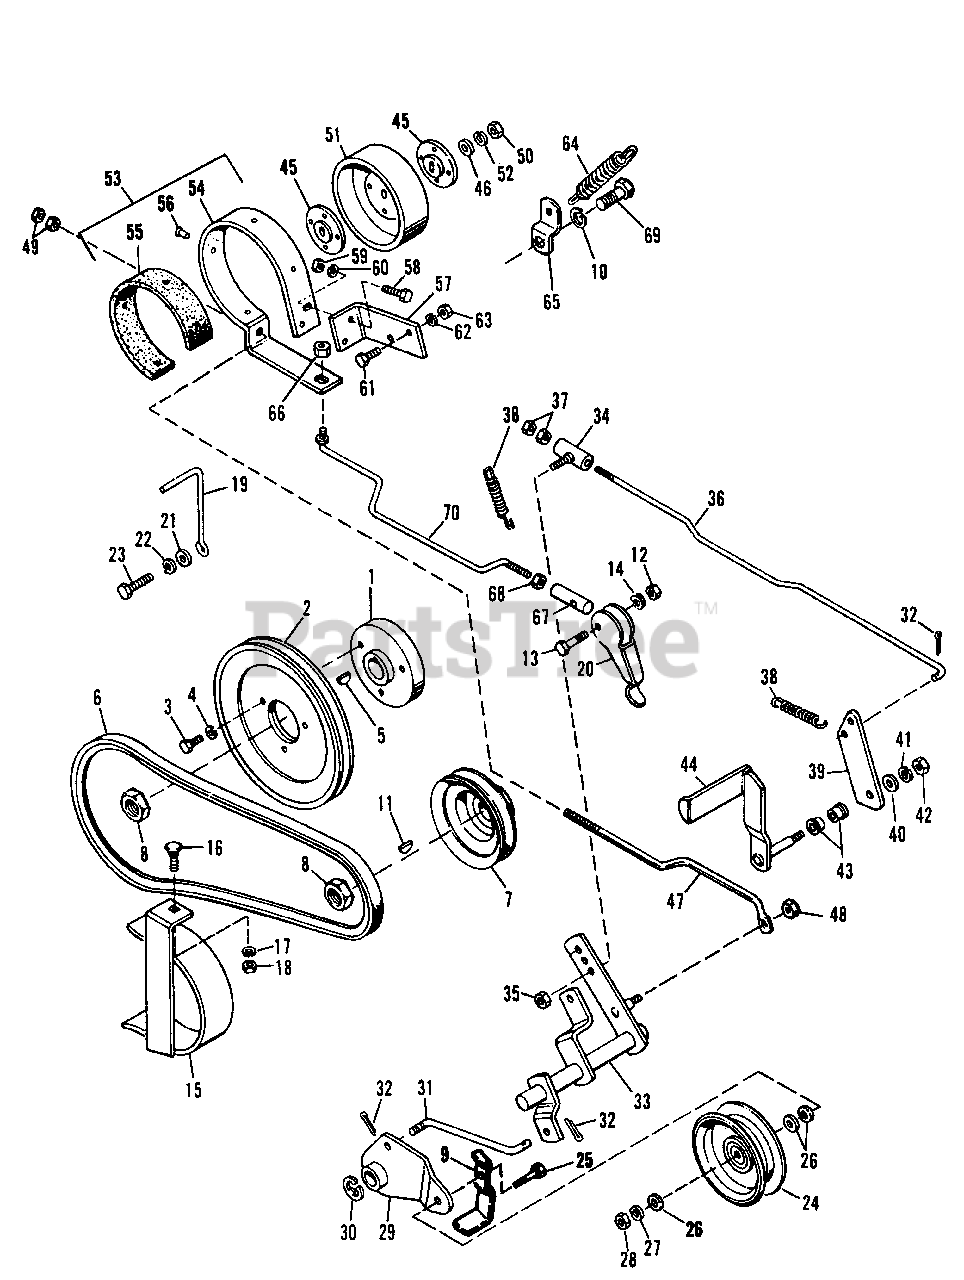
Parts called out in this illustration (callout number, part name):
1	HUB, Pulley
2	PULLEY, Drive
3	CAPSCREW, Hex, 5/16"-18 x 7/8" lg.
4	LOCKWASHER, 5/16"
5	KEY
6	V-BELT, 49.1"
8	NUT, Hex, Jam, 3/4"-16
9	GUIDE, Belt
10	LOCKWASHER, 7/16"
11	KEY
12	NUT, Hex, Full, Lock, 1/4"-20
13	CAPSCREW, Hex, 1/4"-20 x 1-1/4" lg.
14	LOCKWASHER, Double, 1/4"
15	GUARD ASSEMBLY, Belt
16	BOLT, Carriage, 3/8"-16 x 3/4" lg.
17	LOCKWASHER, 3/8"
18	NUT, Hex, Full, 3/8"-16
20	LEVER, Brake, Parking
21	WASHER, Plain, 3/8"
22	LOCKWASHER, 3/8"
23	CAPSCREW, Hex, 3/8"-16 x 1" lg.
24	PULLEY
25	CAPSCREW, Hex, 3/8"-16 x 1-1/2" lg.
26	WASHER, Plain, 3/8"
27	LOCKWASHER, 3/8"
28	NUT, Hex, Full, 3/8"-16
29	LEVER ASSEMBLY, Idler
30	"E" RING
31	LINK, Clutch
32	PIN, Cotter
33	LEVER ASSEMBLY, Pivot
34	GUIDE ASSEMBLY, Rod
35	NUT, Hex, Full, Lock, 5/16-18
36	ROD ASSEMBLY, Brake & Clutch
37	NUT, Hex, Full, 5/16-18
39	ARM, Pedal, Foot
40	WASHER, Plain, 3/8"
41	LOCKWASHER, 3/8"
42	NUT, Hex, Full, 3/8-16
44	PEDAL ASSEMBLY, Foot
45	WASHER, Special
46	WASHER, Plain, 3/8"
47	ROD, Brake
48	NUT, Hex, Full, Lock, 5/16"-18
49	NUT, Hex, Full, 3/8"-16
50	NUT, Hex, Full, 7/16"-14
51	DRUM, Brake
52	LOCKWASHER, 7/16"
53	BAND ASSEMBLY, Brake
54	BAND, Brake
55	LINING, Brake
56	RlVET, #7 x 5/16"
57	BRACKET, Brake Band
58	CAPSCREW, Hex, 3/8"-16 x 1" lg.
59	NUT, Hex, Full, 3/8"-16
60	LOCKWASHER, 3/8"
61	CAPSCREW, Hex, 1/4"-20 x 3/4" lg.
62	LOCKWASHER, 1/4"
63	NUT, Hex, Full, 1/4"-20
65	CLIP, Spring
66	NUT, Hex, Full, 5/16"-18
68	NUT, Hex, Full, Lock, 5/16"-18
69	CAPSCREW, 7/16"-14 x 1-1/4" lg.
70	ROD ASSEMBLY
